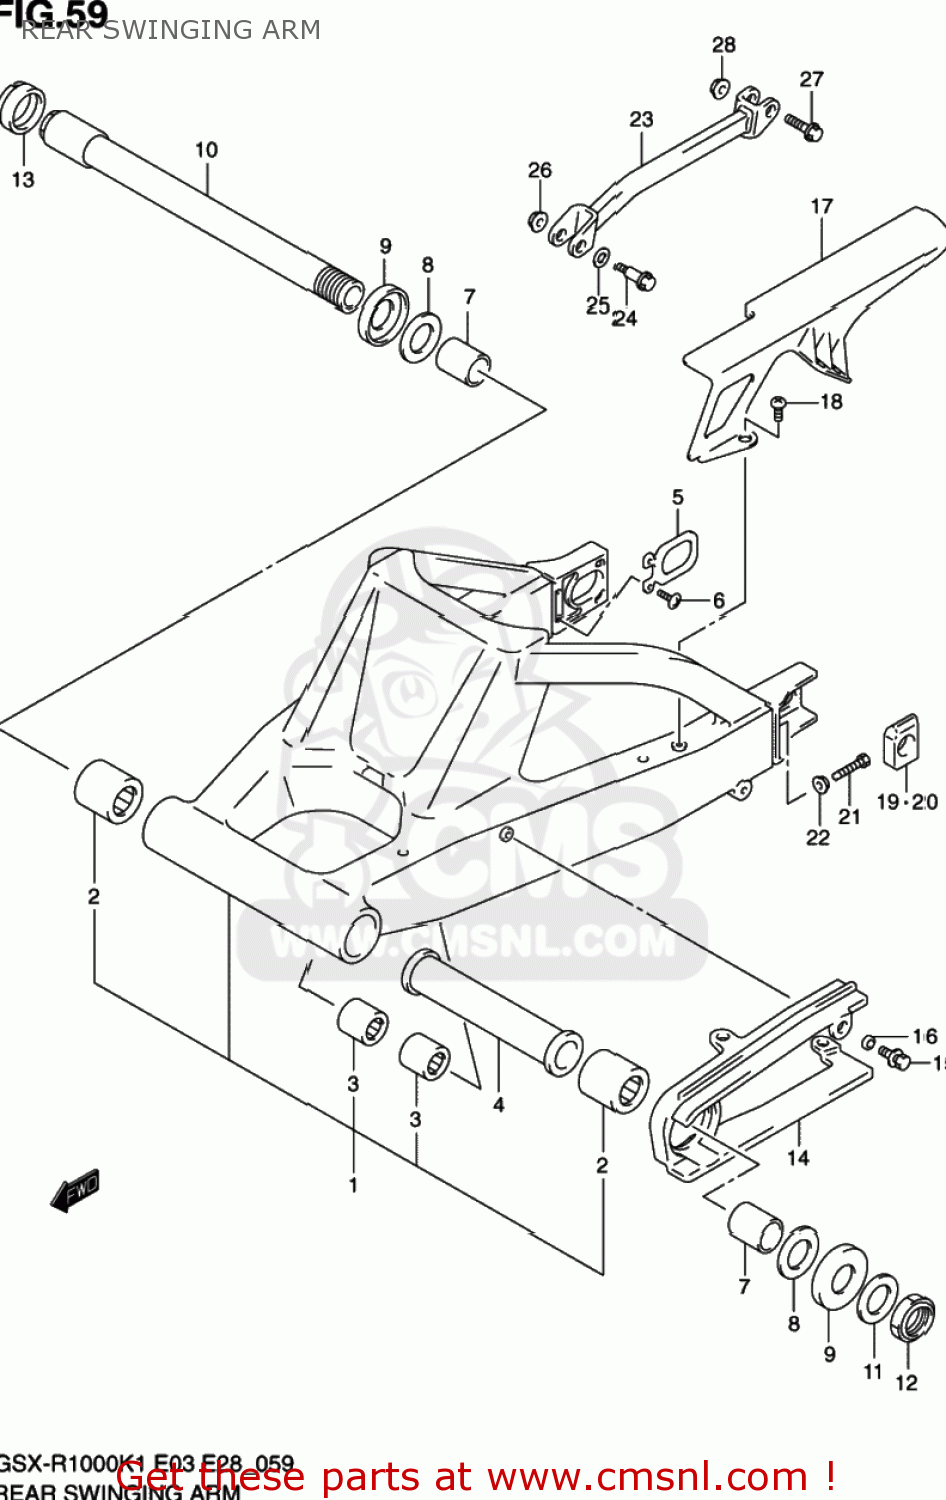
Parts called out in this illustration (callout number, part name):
1	SWINGINGARM ASSY,RR
2	BEARING(30X40X25)
3	BEARING(17X24X20)
4	SPACER,REAR SWING PIVOT,CENTER
5	PLATE,RR SWING ARM BRKT
6	SCREW
7	SPACER,REAR SWING ARM PIVOT
8	WASHER
9	DUST SEAL,RR SWGARM PIVOT
10	SHAFT,RR SWINGINGARM PIVOT
11	WASHER(25.2X42X3.2)
12	NUT
13	NUT,RR SWGARM PIVOT BOLT
14	BUFFER,CHAIN TOUCH DEFENSE
15	BOLT(6X20)
16	SPACER(6.5X10X2.5)
17	CASE,CHAIN
18	SCREW(6X16)
19	ADJUSTER,CHAIN,R
20	ADJUSTER,CHAIN,L
21	BOLT(8X50)
22	NUT
23	TORQUELINK,RR
24	BOLT(8X35.5)
25	WASHER(12.5X20X1)
26	NUT
27	BOLT(10X37)
28	NUT
